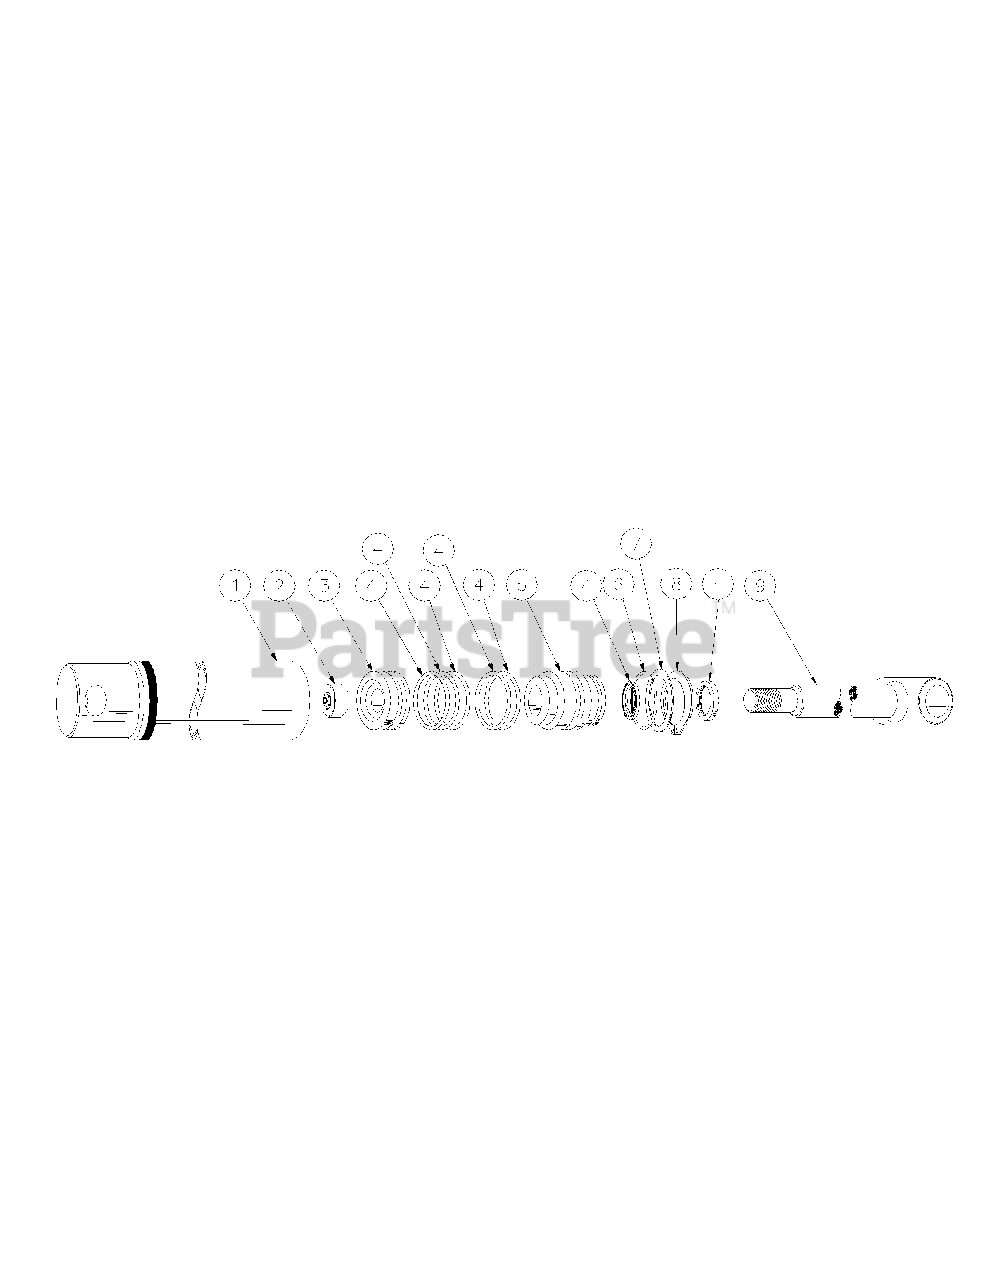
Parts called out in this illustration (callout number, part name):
1	Tube Assembly
6	Retaining Ring
8	Retaining Ring
9	Rod Assembly
